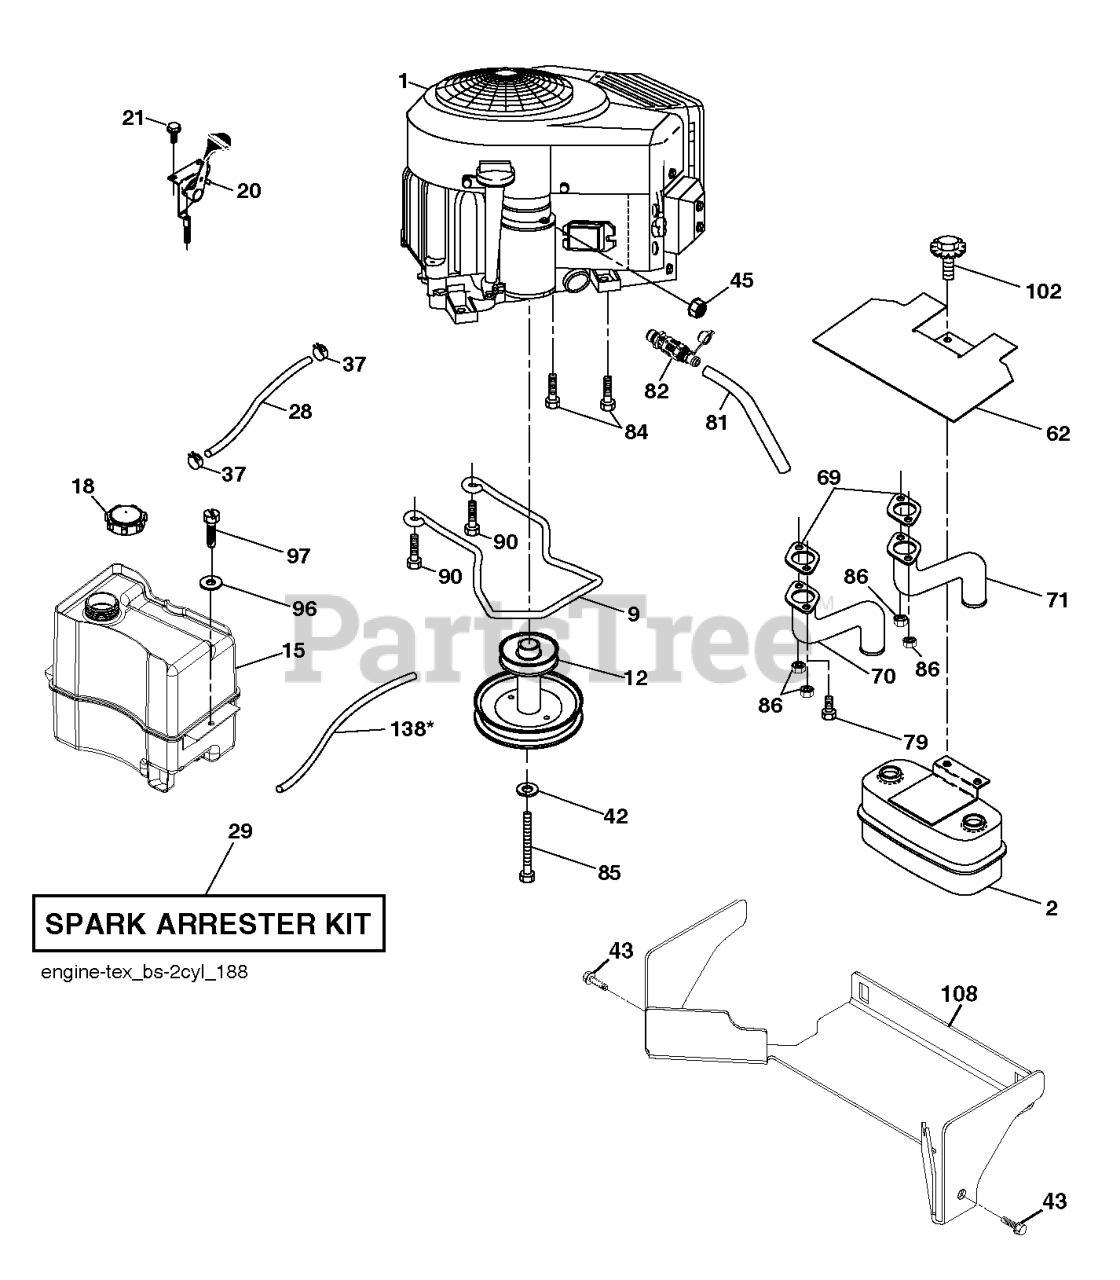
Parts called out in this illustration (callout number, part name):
2	MUFFLER.ASM.TWIN.MNTG.BRACKET
9	KEEPER.BELT.ENG.4.25"2.BLT.431
12	PULLEY.ENGINE
15	TANK.ASSEMBL.2.5GAL.NON-EPA
18	CAP ASM.FUEL.2.25"FR.
20	THROTTLE.COBRA.38"READSTART.BK
20	THROTTLE CABLE
20	CONTROL.TH/CK.COBRA.B&S.TWN.BK
28	LINE.FUEL.20
29	KIT.SPARK ARRESTOR 794945 B&S
37	HOSE CLAMP
43	SCREW 5/16"
45	NUT HEXAGON WITH FLANGE, SERRA
45	Hardware
62	SHIELD.HEAT.MUFFLER
69	GASKET.MUFFLER
70	EXHAUST.TUBE.LH.BS/TWIN
71	EXHAUST.TUBE.RH.B&S.TWIN.INTEK
79	Screws
81	TUBE, DRAIN OIL ASM.
82	VALUE.OIL.DRAIN
84	SCREW 3/8-16X1
84	SCREW.3/8-16
85	BOLT.HEX.7/16-20X4.GR5.1.5BLUE
86	NUT.HEX.FLANGE.TOPLOCK
90	SCREW 3/8-16X1
97	SCREW HEXWSHR 1/4-20X3/4
102	SCREW
108	SHIELD.CLUTCH.BLACK.MS431
